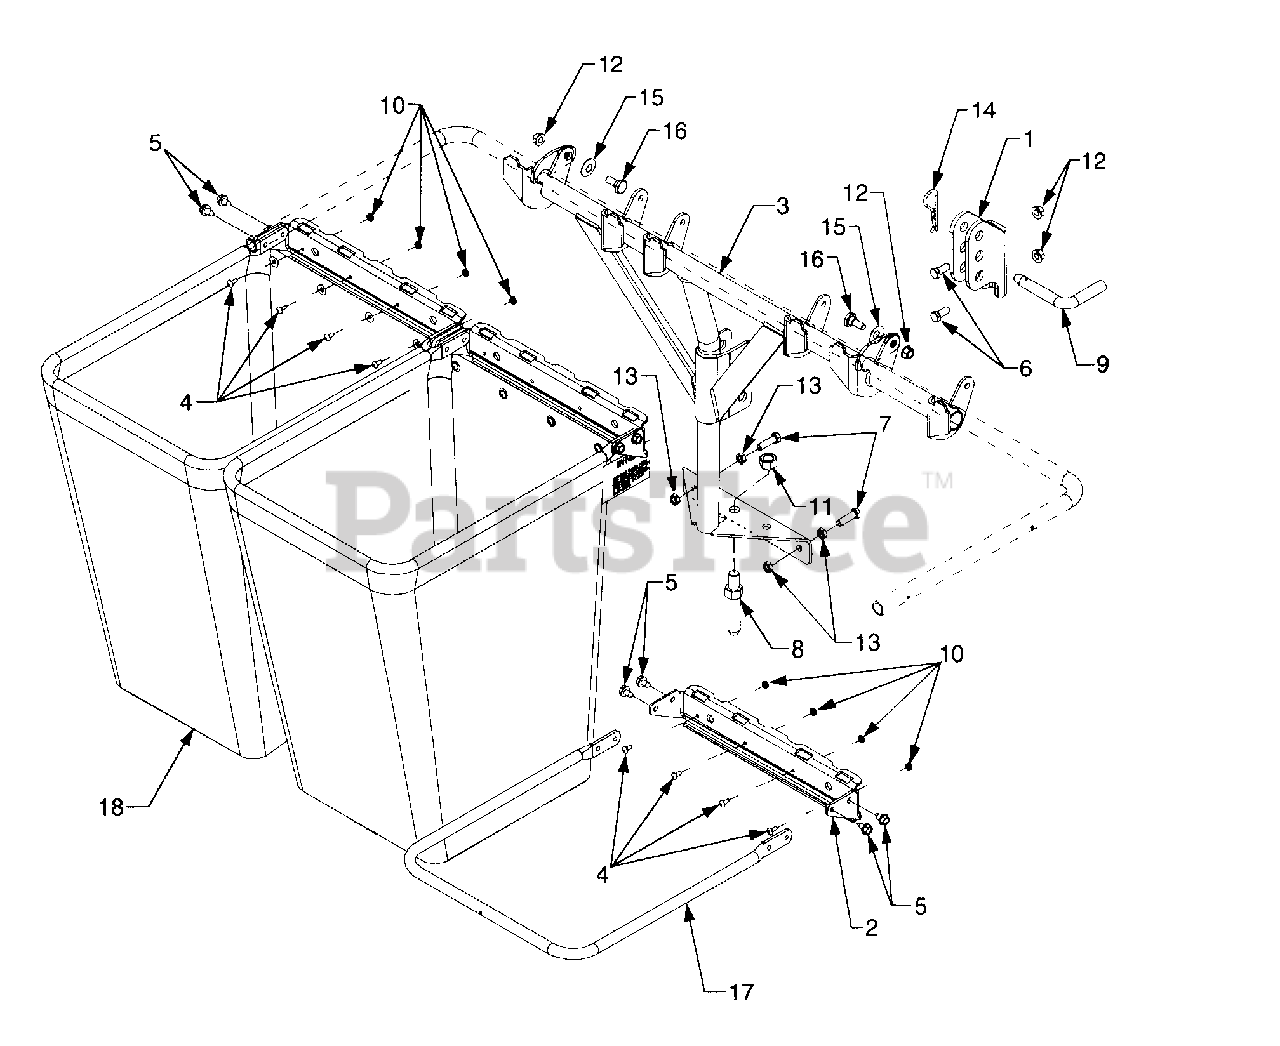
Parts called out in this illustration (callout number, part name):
1	Bracket, Hitch
2	Bracket, Bag Frame Hanger
3	Mounting Tube Assembly
4	Screw, Truss Hd. Mach. 10-24 x .5
5	Screw, Hex Wash. Hd. Tapp 5/16-18 x .625
6	Screw, Hex Cap 3/8-16 x .880 GR5
7	Screw, Hex Cap 3/8-16 x 1.25 GR5
8	Stud, Adapter
9	Pin, Right Angle Clevis
10	Nut, Hex Sems, 10-24
11	Nut, Hex, 5/8-18 GR5
12	Nut, Hex Flange Lock, 3/8-16
13	Nut, Hex Jam, 3/8-16 GR5
14	Pin, Internal Cotter
15	Washer, Belleville, .51 x 1.14 x .04
16	Screw, Shoulder.50 x .27: 3/8-16
17	Tube, Grass Bag Frame
18	Bag, Grass Catcher
